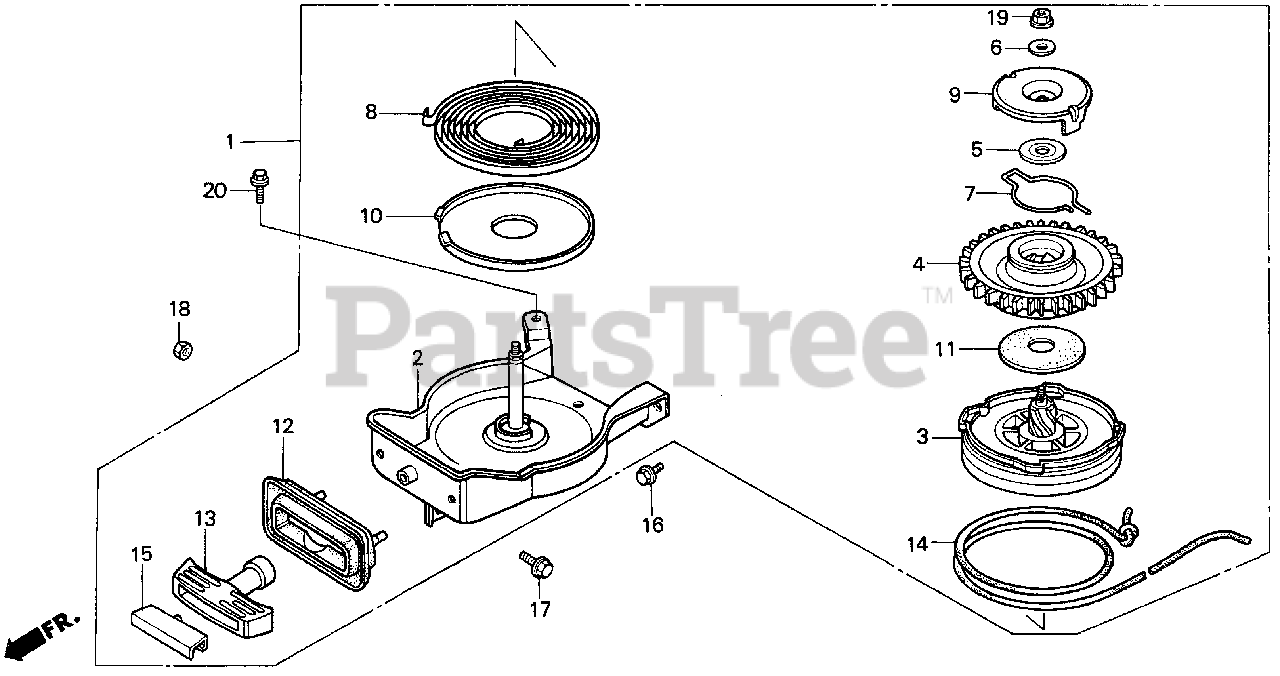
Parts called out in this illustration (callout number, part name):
1	STARTER ASSY., RECOIL *TBLACK* (BLACK)
2	CASE, RECOIL STARTER
2	CASE, RECOIL STARTER *TBLACK* (BLACK)
3	PULLEY, RECOIL STARTER
4	GEAR, STARTER
5	WASHER, THRUST
6	WASHER
7	SPRING, FRICTION
8	SPRING, STARTER RETURN
9	RETAINER, SPRING
10	HOLDER, SPRING
11	RUBBER, CUSHION
12	RUBBER, ENGINE COVER SEAL
13	GRIP, STARTER
14	ROPE, RECOIL STARTER (#5.5X79") (N/A: USE P/N 08555-ZG921-11)
16	BOLT, FLANGE (6X12)
17	BOLT, FLANGE (6X16)
18	NUT, HEX. (6MM)
19	NUT, FLANGE (6MM)
20	BOLT, FLANGE (6X16)
